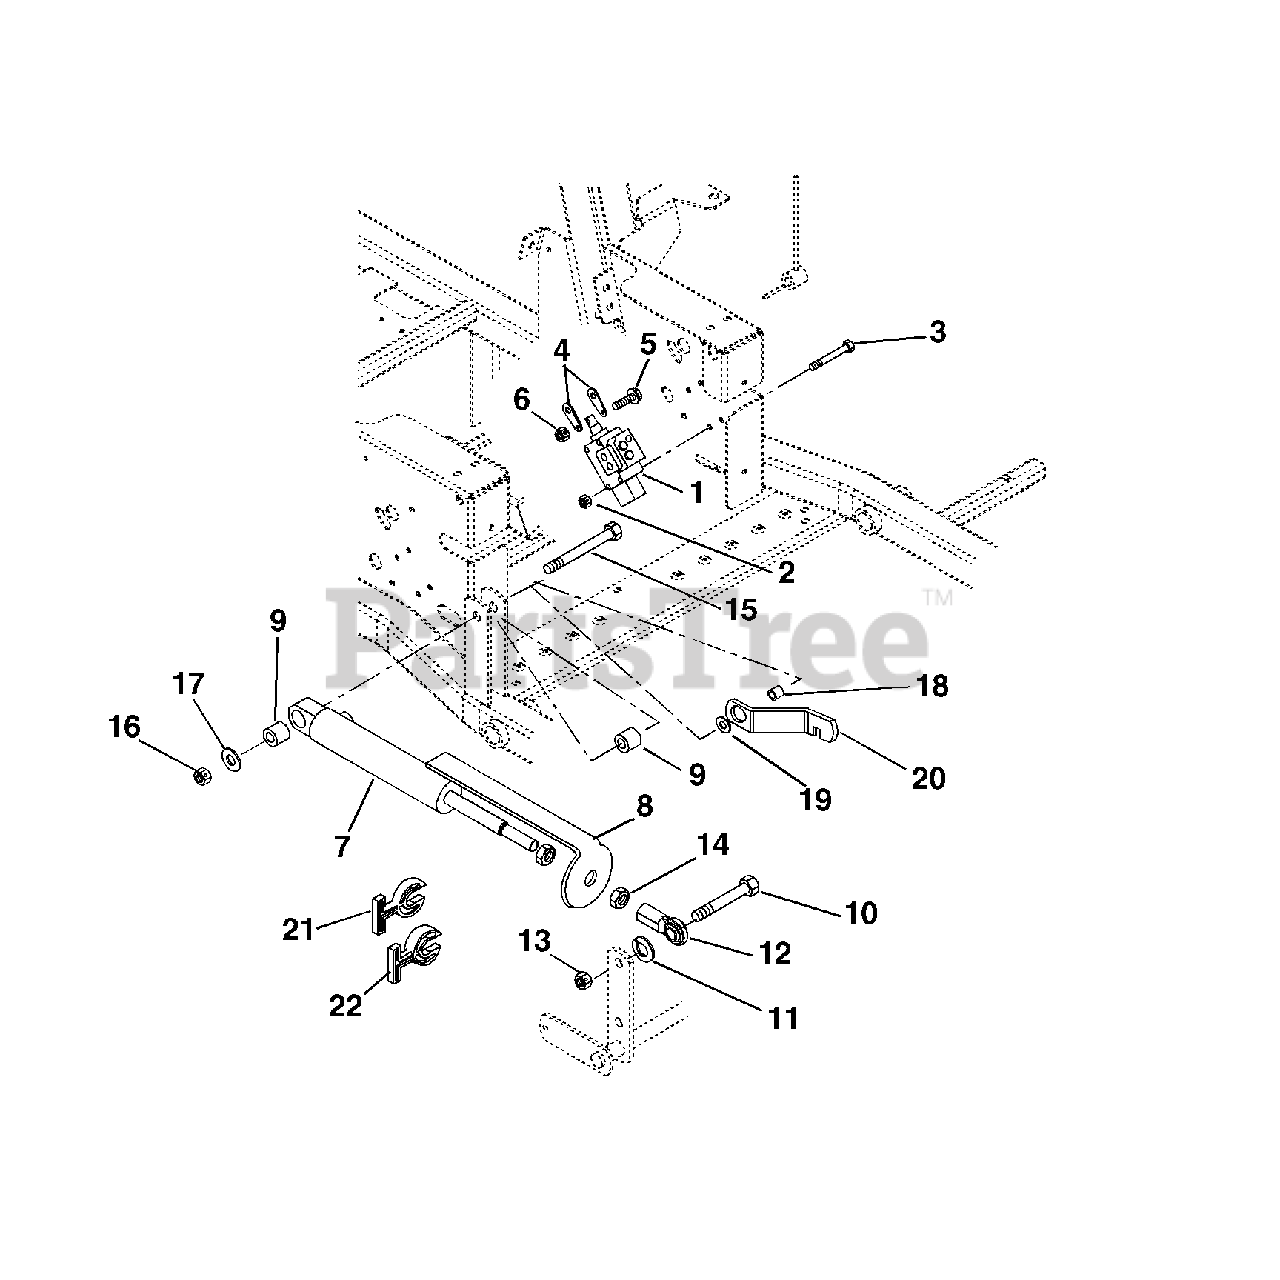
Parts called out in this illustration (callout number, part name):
1	Valve, Hydraulic Lift
2	Nut-Locking-Nylon .25-20
3	Bolt-Hex .25-20 x 2.75 Grade 5
5	Screw-Machine 10-24 x 1.00 Hex Washer Head
6	Nut-Locking-Nylon 10-24 with Insert
7	Cylinder-Hydraulic Lift
8	Strap-Height of Cut Indicator
9	Bushing .516 x 1.000 x 1.050
10	Bolt-Hex .62-11 x 2.25 Grade 8
11	Washer-Lock .62 x .156
12	Rod End-Right Hand-Female 5/8
13	Nut-Locking-Center .62-11
14	Nut-Jam .625-18
15	Bolt-Hex .50-13 x 3.75 Grade 5
16	Nut-Locking-Center .50-13
17	Washer-Flat-Steel .515 x 1.625 x .25
18	Bushing-Flange .515 x .75 x .275 x 1.12
19	Wave-Washer .76 x 1.12 x .08
21	Stop, Cylinder .34 Thick
22	Stop, Cylinder .68 Thick
